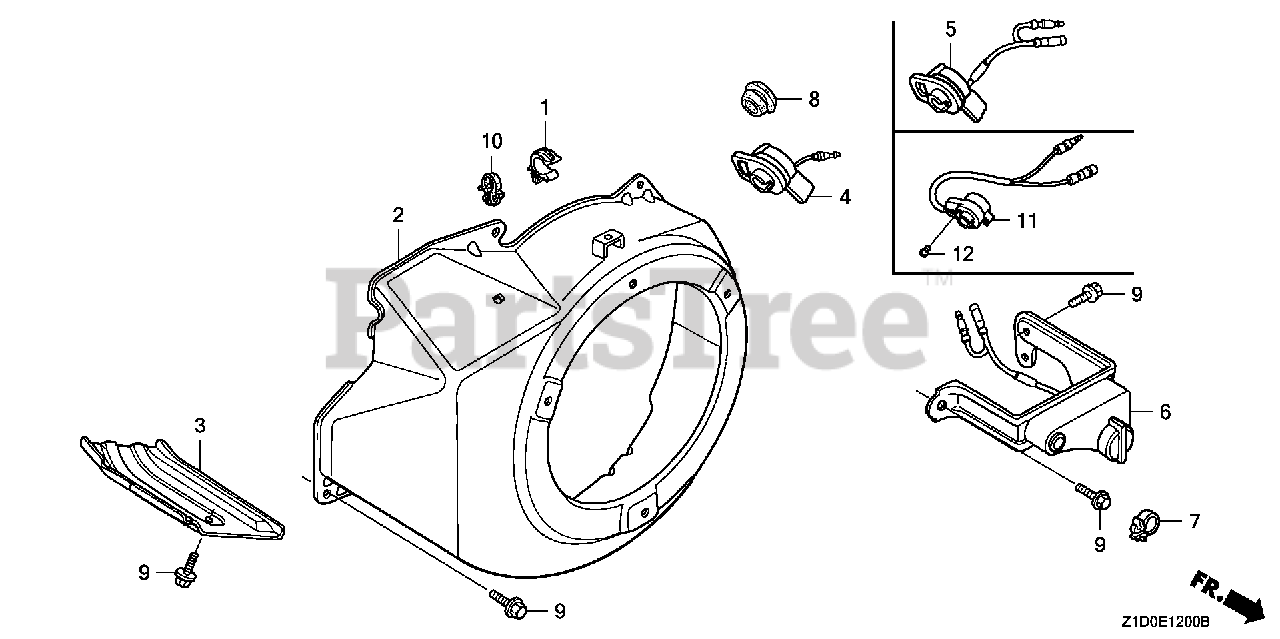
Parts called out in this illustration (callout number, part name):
1	CLIP, TUBE
2	COVER, FAN *NH1* (BLACK)
2	COVER, FAN *R280* (POWER RED)
9	BOLT, FLANGE (6X12) (CT200)
11	SWITCH ASSY., ENGINE STOP
12	SCREW, TAPPING (3X6) (PO)
